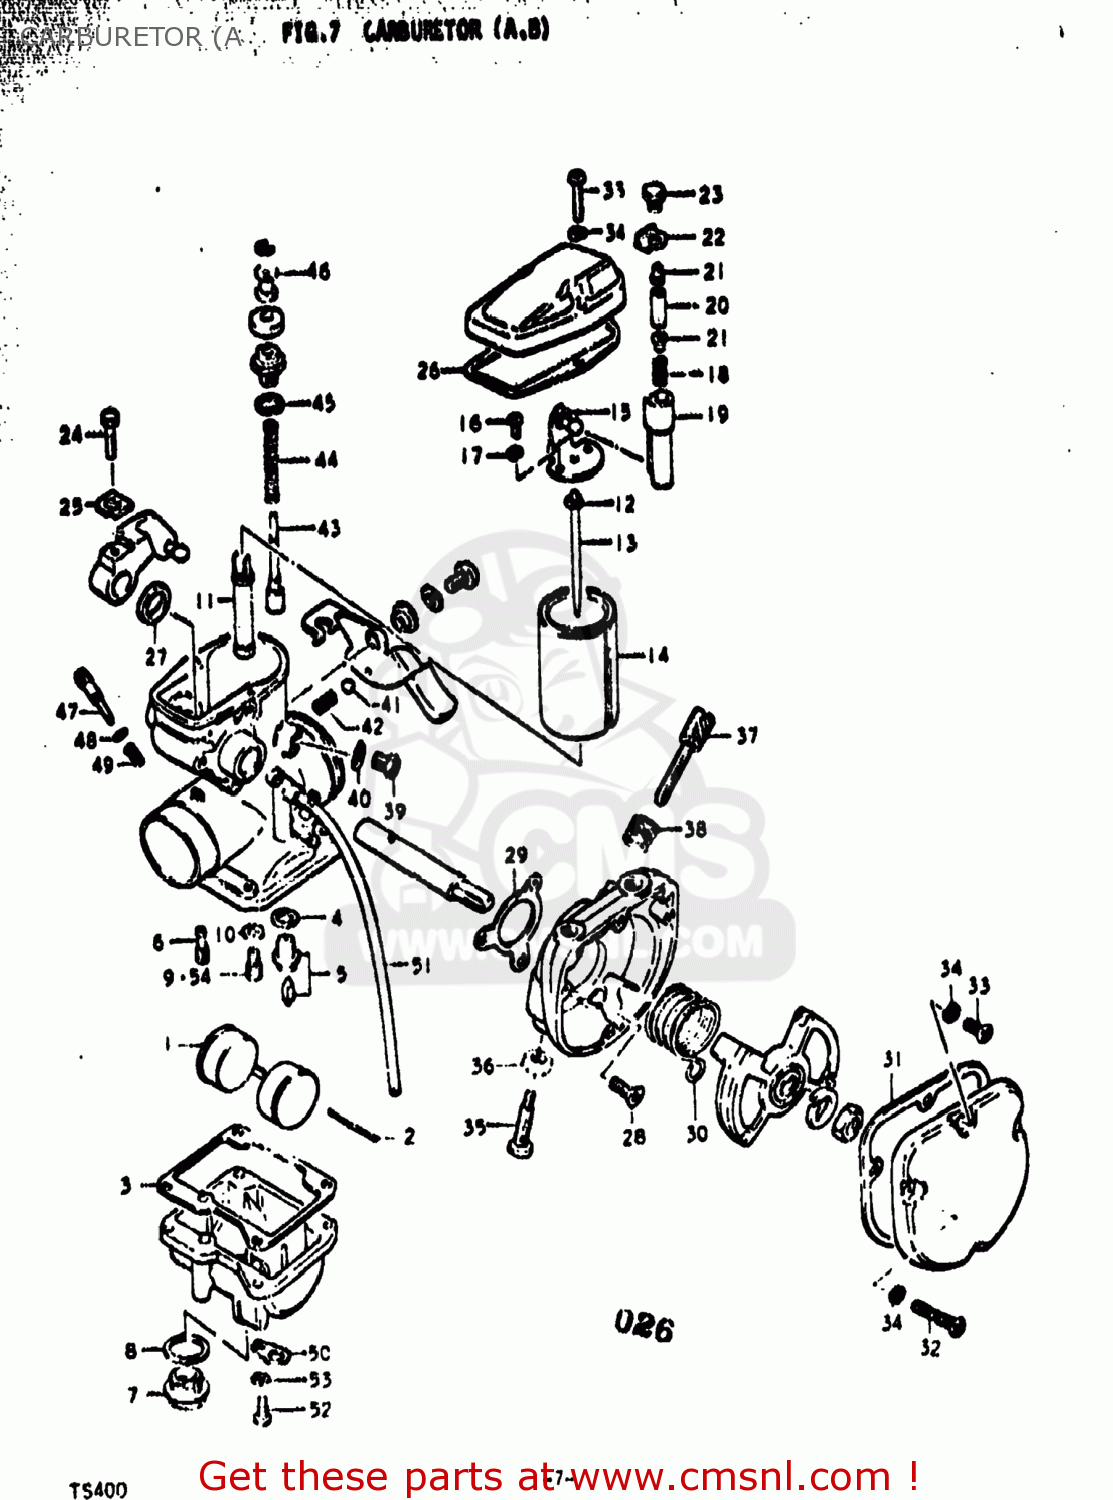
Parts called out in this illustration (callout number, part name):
1	FLOAT
2	PIN,FLOAT
3	GASKET,FLOAT CAHMBER (NAS)
4	GASKET,MAIN JET HOLDER (NAS)
5	VALVE ASSEMBLY,NEEDLE
6	JET
7	SCREW,GUIDE
8	O-RING
9	JET
10	WASHER
11	JET,NEEDLE
12	CLIP
13	NEEDLE JET
14	VALVE,THROTTLE
15	CONNECTOR
16	SCREW
17	LOCK WASHER
18	SPRING
19	LEVER ASSEMBLY
20	SPRING
21	PIN,CARBURETOR
22	PLATE,CARBURETOR
23	SCREW
24	BOLT
25	RING
26	GASKET,MIXING CHAMBER (MCA)
27	RING
28	SCREW(5X14)
29	GASKET,CARBURETOR CASE
30	SPRING
31	GASKET,CARBURETOR CASE
32	SCREW
33	SCREW
34	LOCK WASHER
35	SCREW
36	NUT
37	SCREW,THROTTLE STOP
38	SPRING,THROTTLE SCREW
39	BOLT
40	GASKET,THRO VALVE INSPECTION (NAS)
41	BALL,STARTER SHAFT
42	SPRING,STARTER SHAFT
43	VALVE,STARTER
44	SPRING
45	O-RING
46	RING
47	SCREW,PILOT AIR ADJUSTING
48	O RING
49	SPRING
50	PLATE
51	HOSE
52	SCREW
53	LOCK WASHER
54	JET
